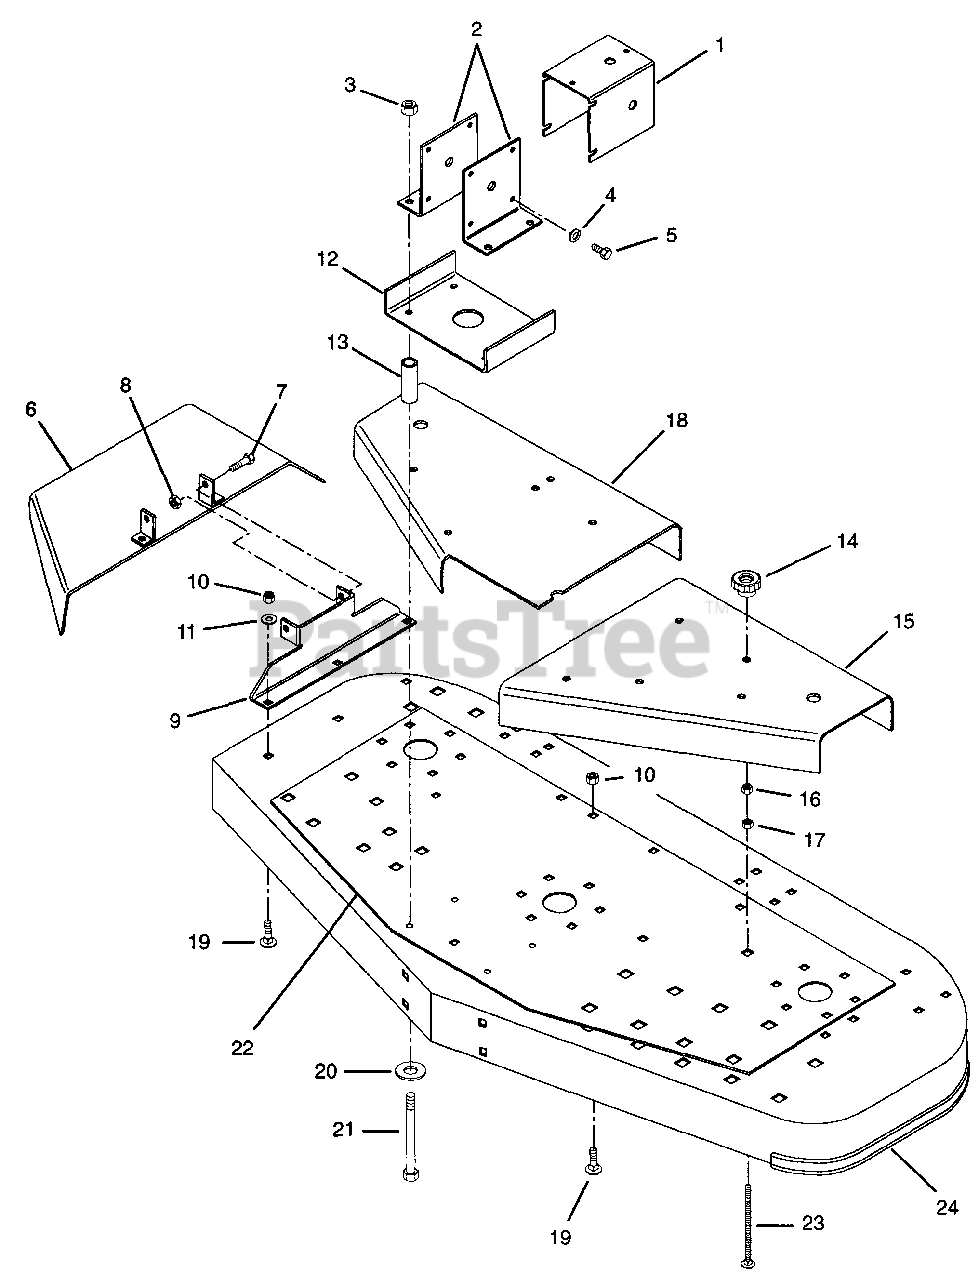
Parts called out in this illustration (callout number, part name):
1	Shield, U-Joint
2	Bracket, Gearbox Mounting
3	Nut-Locking-Nylon .50-13 Grade 5
4	Washer-Lock .375 x .094
5	Bolt-Hex .380-16 x .875
6	Weldment, Discharge Chute
7	Bolt-Hex .25-20 x .875
8	Nut-Locking-Nylon .250-20 Grade 2
9	Bracket, Discharge
10	Nut-Locking-Nylon .375-16 Grade 2
11	Washer-Flat-Steel .406 x .812 x .065
12	Plate, Support
13	Spacer .562 x 1.00 x 2.00
14	Knob
15	Cover, Belt Silkscreen
16	Nut-Locking-Nylon .312-18 Grade 2
17	Nut-Jam .312-18
18	Cover, Belt Right Hand
19	Bolt-Round Head Square Neck .38-16 x 1.0
20	Washer-Flat-Steel .531 x 1.062 x .095
21	Bolt-Hex .50-13 x 3.75
22	Plate, Deck Support
23	Bolt-Round Head Square Neck .31-18 x 4.0
24	Weldment, 60" Mower Deck
